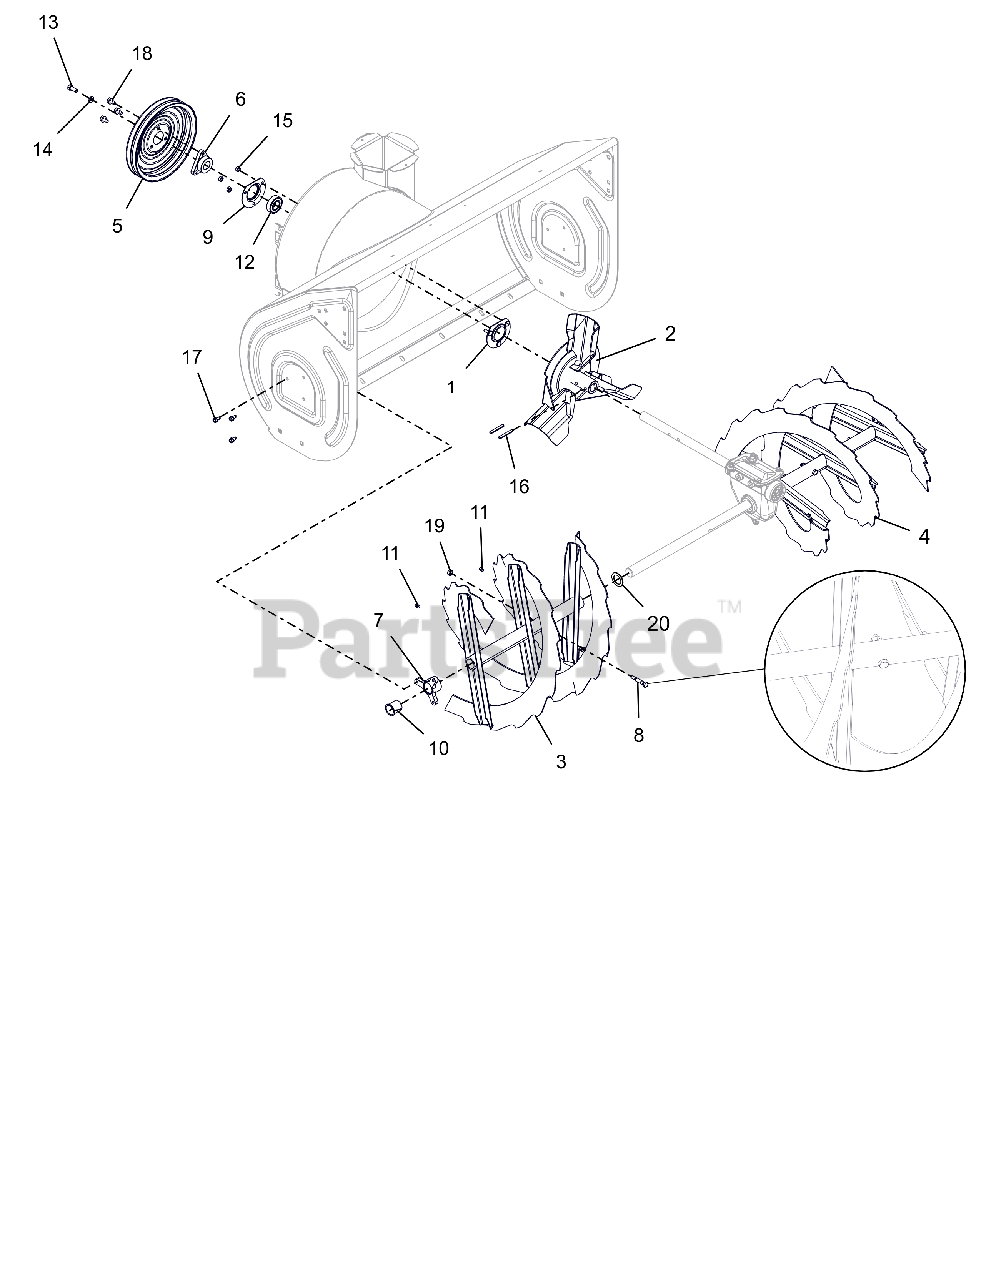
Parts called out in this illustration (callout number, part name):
1	BEARING FLANGE
2	IMPELLER, 3 BLADE-14"
3	RAKE, RH-36"(1 ID X 15.75 OD)
4	RAKE, LH-36" (1 ID X 15.75 OD)
5	PULLEY, SPIN FORM DUAL GROOVE
6	PULLEY HUB, D-BORE .87 PRO
7	BUSHING, RAKE SHAFT 1"
8	SHEAR BOLT SERVICE ASSEMBLY
9	BEARING FLANGE
10	BSHG-FLG SPLIT NYLINER 1.0" HP
11	ZERK,FITTING .25X.125 DRIVE IN
12	BRG-BALL .876X1.75X.50 RSTFP
13	BLT, HEX .31-24X.750 G5 ZCC
14	WSHR, LK-HVY .312X.097 ZCC
15	NUT,LK-CTR .25-20 GA ZCC
16	PIN-ROLL .250X1.75
17	SCR-TAP .25-20X.50 HWH ZCC
18	SCR,TAP .312-18X.50 HWH TR ZCC
19	NUT,LK-CTR .31-18 GA ZCC
20	WSHR, FLT 1.010X1.505X.062 ZCC
